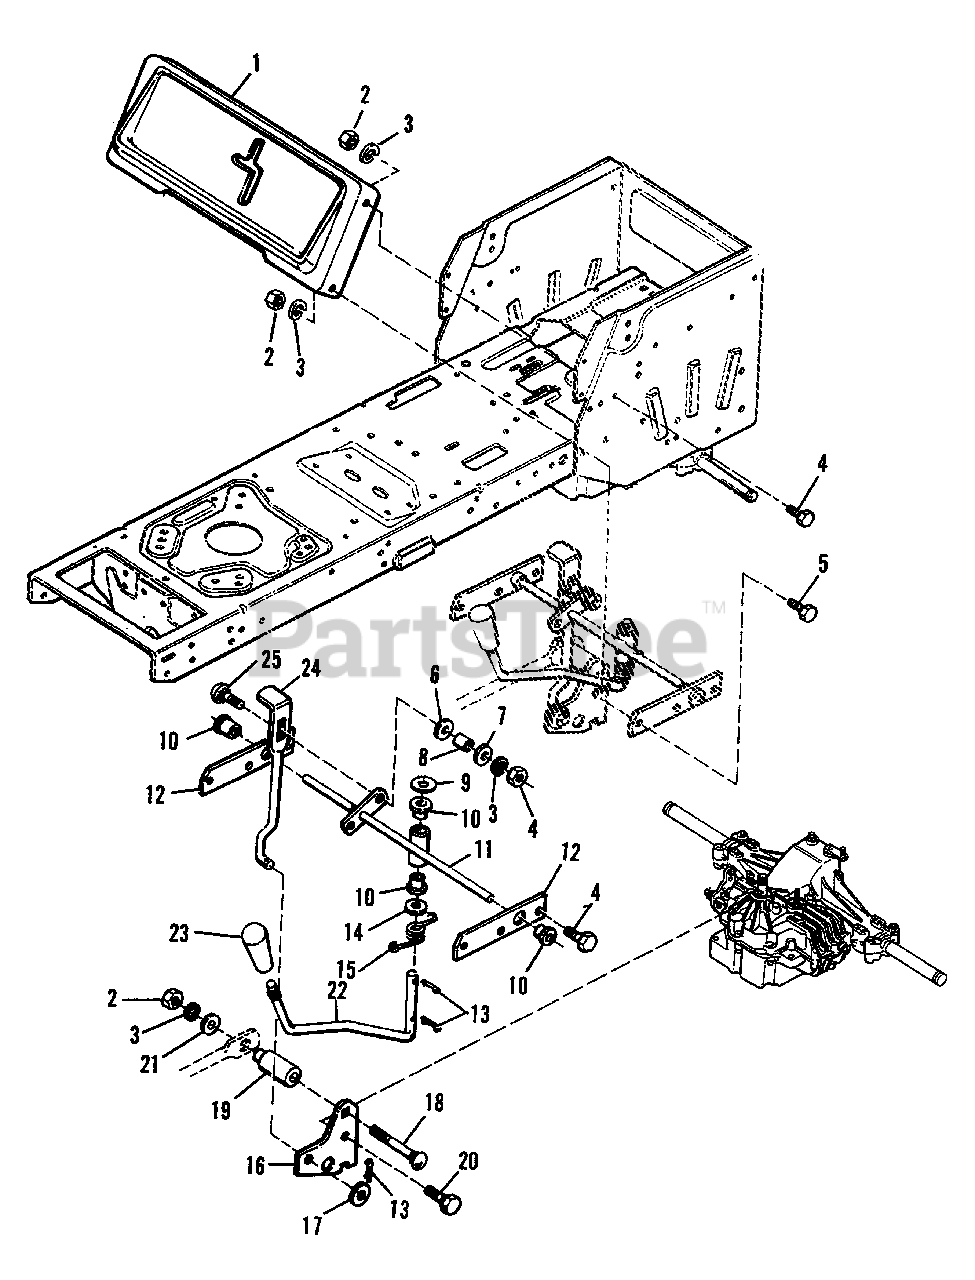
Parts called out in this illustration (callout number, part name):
1	PANEL, Shift
2	NUT, Hex, 5/16-18
3	LOCKWASHER, Spring, 5/16
4	SCREW, Taptite, 5/16-18 x 1/2
5	SCREW, Taptite, 1/4-20 x 1/2
6	WASHER, 11/32 x 1 x 1/8
7	WASHER, Plain, 11/32 x 3/4 x 1/16
9	WASHER, Plain, 1/2 x 1 x 3/32
11	SHIFT ROD ASSY.
12	BRACE, Shift Panel
13	COTTER PIN, 15/16 x 3/4
14	WASHER, Plain, 1/2 x 1-1/4 x 5/64
15	SPRING, Torsion
16	CONTROL LEVER
17	WASHER, Plain, 13/32 x 7/8 x 5/64
18	CARRIAGE BOLT, 5/16-18 x 1-1/4
20	CAPSCREW, Hex Hd., 5/16-18 x 1
21	WASHER, Plain, 11/32 x 3/4 x 5/64
22	ROD, Shift
23	KNOB, Large
24	ROD, Control
25	CARRIAGE BOLT, 5/16-18 x 1
